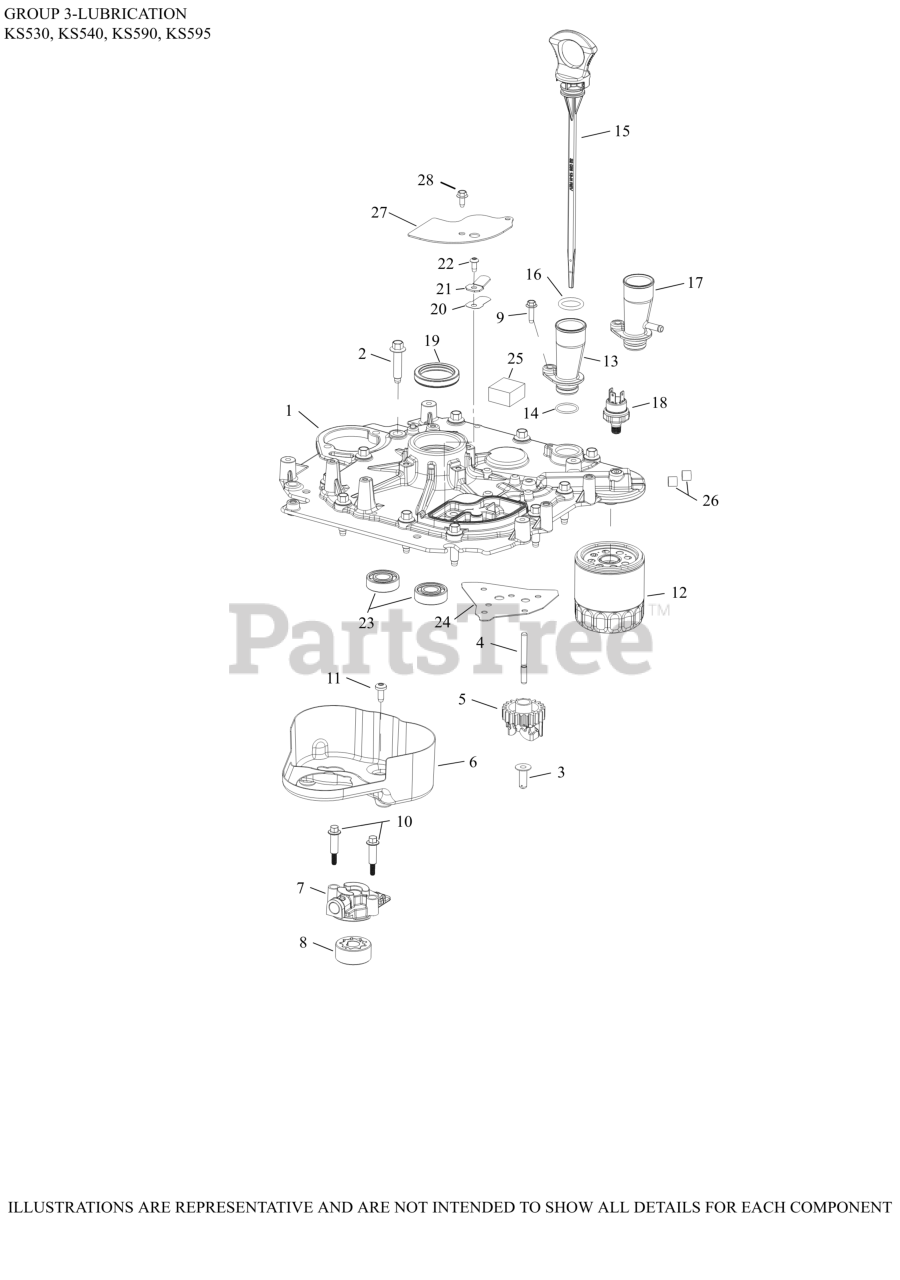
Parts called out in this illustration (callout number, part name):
1	PLATE, CLOSURE ASSY
2	SCREW, HEX FLANGE
3	PIN, GOVERNOR REGULATING
4	SHAFT, GOVERNOR CROSS
5	KIT, GOVERNOR GEAR
6	BAFFLE, OIL
7	HOUSING, OIL PUMP ASSY
8	PUMP ASSY, OIL
9	SCREW, THD FRM-USE 25 086 473-S
10	SCREW, SHOULDER THREAD FORMING
11	SCREW, THREAD FORMING
12	OIL FILTER
15	DIPSTICK, ASSY
17	TUBE, DIPSTICK ASSY
19	SEAL, OIL
26	PLUG, CTSK PIPE 1/8"
